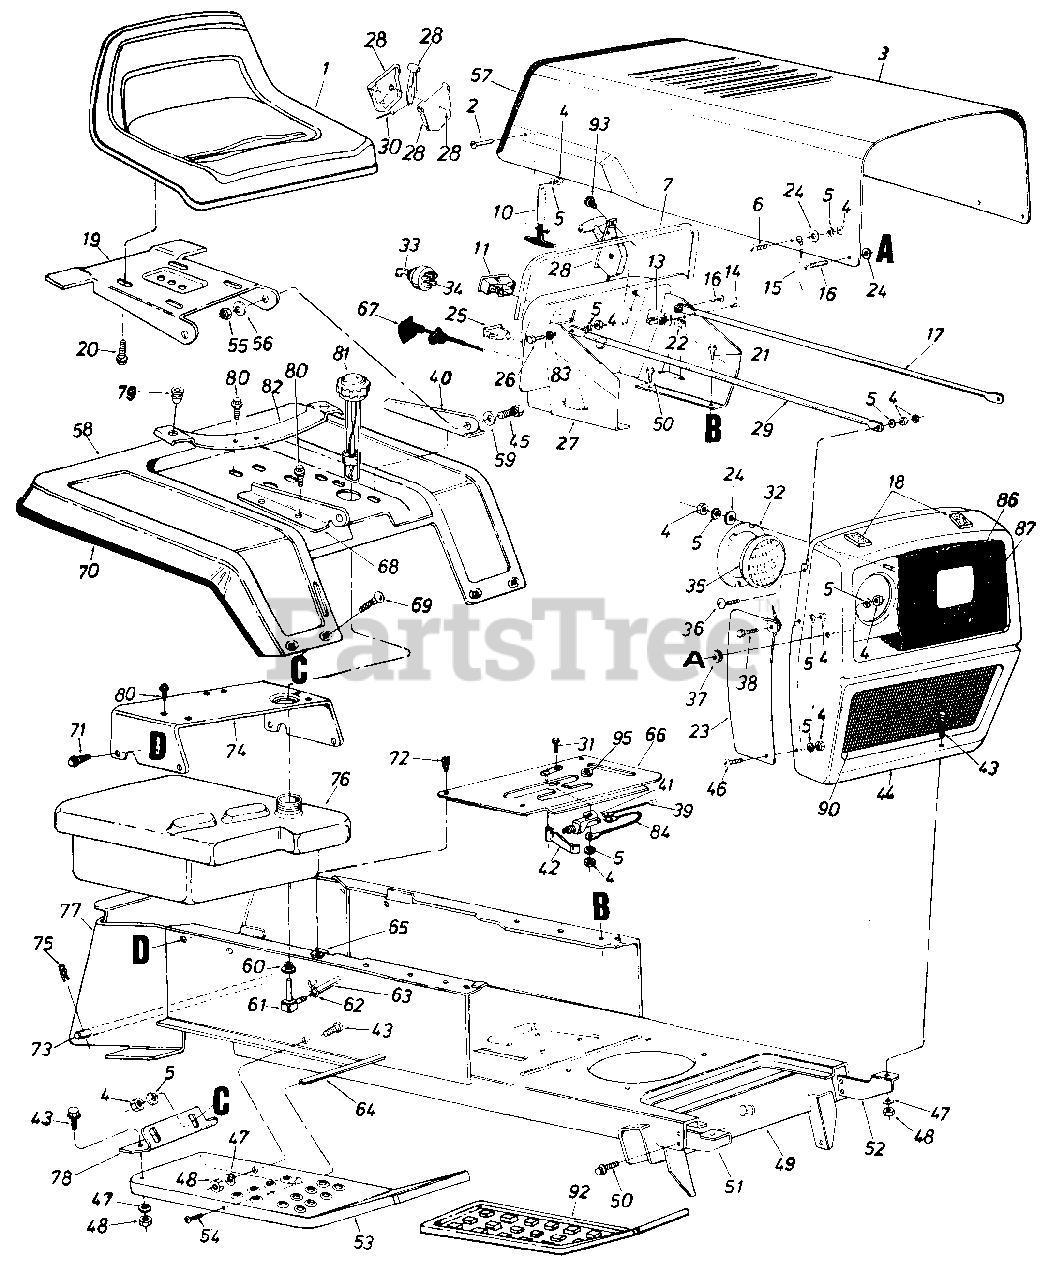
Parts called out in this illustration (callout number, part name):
1	Seat Assembly
2	Truss Mach. Scr. 1/4-20 x .50" Lg.
5	L-Wash. 1/4" Scr.
6	Truss Mach. Scr. 1/4-20 x .50" Lg.
7	Vinyl Molding Strip 29"
10	Hood Latch Ass'y.
11	Ammeter
13	Circuit Breaker 8 Amp.
14	Hex Tap Scr #10 x .50" Lg.
15	Hood Stop
16	Truss Mach. Scr. 1/4-20 x .75" Lg.
17	Grille Positioning Rod
18	PVC Foam Strip 1/2 X 1.00" x 2.00" Lg.
20	Hex Wash. Hd. AB-Tap Scr. 318 x .75" Lg.
21	Hex Thd. Rolling Scr. 1/4" x .50" Lg.
22	Speed Nut #1 OZ
23	Grille Side Panel R.H.
23	Grille Side Panel L.H.
24	Fl-Wash. 1/4" I.D.
25	Light Switch
26	Truss Hd. Scr. 1/4-20 x 1.00" Lg.
27	Dash Panel Ass'y.
28	Throttle Control Box Comp.
29	Grille Positioning Rod
30	Throttle Control Cable
31	Hex Bolt 1/4-20 x .50" Lg.
32	Head Lamp Retainer
33	Ignition Key
34	Ignition Switch
35	Head Lamp
36	Truss Machine Scr. 1/4-20 x .75" Lg.
37	Rubber Wash. .50" I.D. x 1.00 O.D. x .25 Thk.
38	Truss Mach. Scr. 1/4-20 x .50" Lg.
39	Reverse Lockout Wire Harness
40	Seat Bracket L.H.
41	Safety Switch
42	Switch Actuator Spring Lever
43	Hex Scr. 5/16-18 x .75" Lg.
44	Grille Ass'y.
45	Hex Bolt 5/16-18 x .75" Lg.
46	Truss Mach. Scr. 1/4-20 x .50" Lg.
47	L-Wash. 5/16" I.D.
48	Hex Nut 5/16-18 Thd.
49	Lower Frame Ass'y.
50	Hex Thd. Rolling Scr. 5/16" x.75" Lg.
51	Grille Mount Brkt. R.H.
52	Grille Mount Brkt. L.H.
53	Running Board R.H.
53	Running Board L.H.
54	Truss Mach. Scr. 5/16-18 x .75" Lg.
55	Hex Cent. L-Nut 5/16-18 Thd.
56	Bell-Wash. .34" I.D. x .88 0 O.D.
57	Vinyl Moulding Strip 30"
60	Bushing
61	90ø Nipple
62	Hose Clamp 3/8"
63	Gas Line 46" Lg.
64	Running Board Rod
65	Speed Nut #10-24
66	Transmission Cover Ass'y.
67	Choke Control Comp.
68	Seat Bracket R.H.
69	Carr. Bolt 1/4-20 x .50" Lg.
70	Trim Strip 81" Lg.
71	Hex Thd. Rolling Scr. 5/16-24 x .75" Lg.
72	Truss Hd. Scr. #10 x .50" Lg.
73	Hitch Rod
74	Seat Mounting Channel
75	Internal Cotter Pin
76	Gas Tank
77	Hitch Plate
78	Fender Brkt. R.H.
80	Hex Wash. Hd. Self-Tap Scr. 5/16-18 x .50" Lg.
81	Gas Gauge
82	Seat Spring
83	External Wash. 1/4" I.D.
84	Electric Wire
86	Headlight Bezel
87	Hex Wash. Hd. F-Tap Scr. #8-32 x .38" Lg.
90	Grille Screen
92	Foot Pad
93	Truss Mach. AB-Tap Scr. #10 x .50" Lg.
95	Snap Bushing
